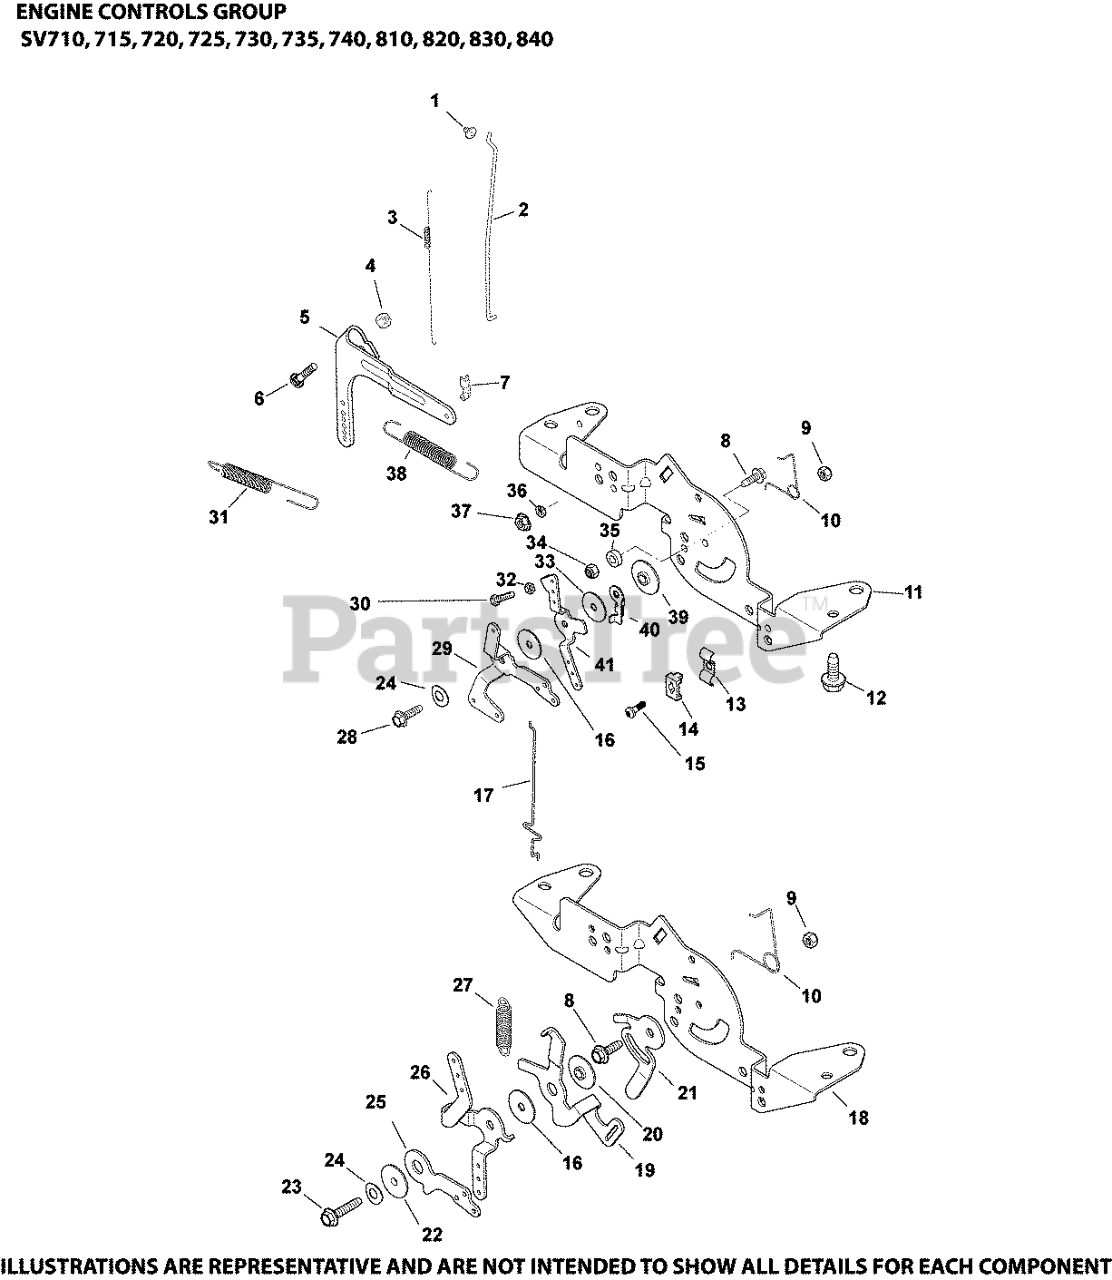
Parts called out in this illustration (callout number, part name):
1	BUSHING, LINKAGE RETAINING
2	LINKAGE, THROTTLE
3	SPRING, LINKAGE
4	NUT, FLG M6X1.0
5	LEVER, GOVERNOR - (#2409069S)
6	BOLT, RD HD SQ NECK M6X1.0X25
7	BUSHING, THROTTLE LINKAGE
8	SCREW, THREAD FORMING
9	NUT, LOCK M5X.8
10	SPRING, CHOKE RETURN
12	SCREW, THREAD FORMING
14	CLAMP, CABLE
15	SCREW, LBD THD FRM M5x0.8x16 - USE 25 086 405-S
16	WASHER, FLAT 5.5 MM
17	LINKAGE, CHOKE
18	BRACKET, CONTROL USE 32 126 18-s
22	SPACER, CONTROL ASSEMBLY
24	WASHER, SPRING 1/4"
28	SCREW, THREAD FORMING - USE 25 086 473-S
29	LEVER, CHOKE
30	SCREW, SLT HD CAP M4X0.7X25
31	SPRING, GOVERNOR (PURPLE)
32	NUT, M4X0.7
33	WASHER, FLAT 5 MM
38	SPRING, GOVERNED IDLE
40	LEVER, THROTTLE ACTUATOR
41	LEVER, THROTTLE CONTROL
